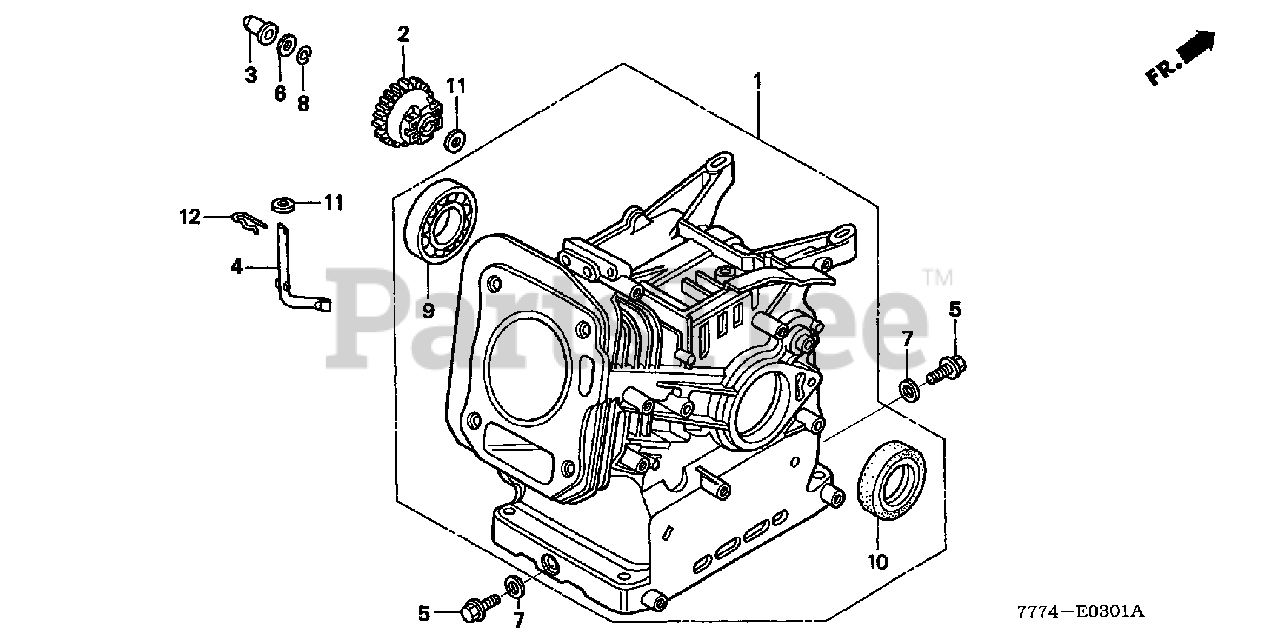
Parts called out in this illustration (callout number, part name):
1	CYLINDER ASSY.
2	GOVERNOR ASSY.
3	SLIDER, GOVERNOR
4	SHAFT, GOVERNOR ARM
5	BOLT, DRAIN PLUG
6	WASHER, THRUST (6MM)
7	WASHER, DRAIN PLUG (10.2MM)
8	CLIP, GOVERNOR HOLDER
9	BEARING, RADIAL BALL (6205)
10	OIL SEAL (25X41X6)
11	WASHER, PLAIN (6MM)
12	PIN, LOCK (8MM)
